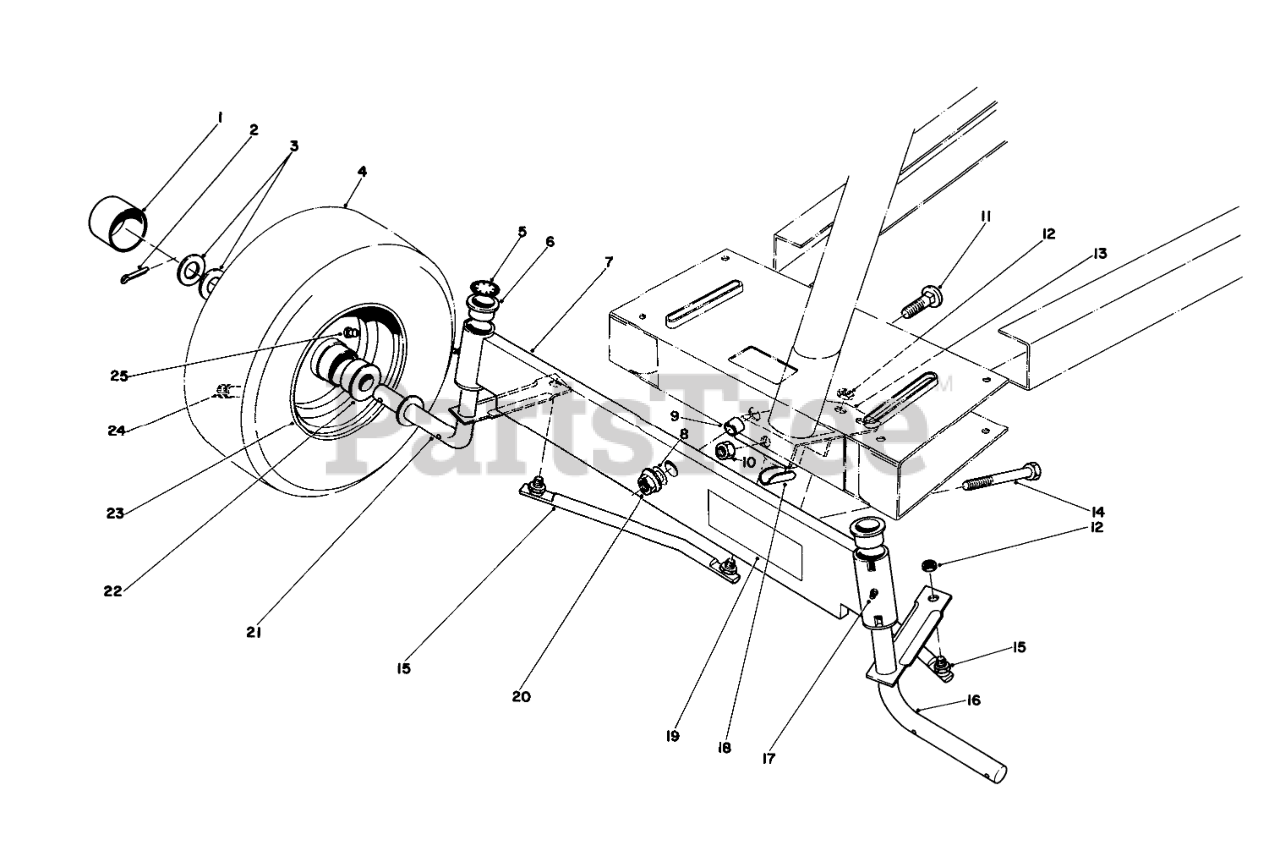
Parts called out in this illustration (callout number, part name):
1	Hub Cap
2	PIN-COTTER
3	WASHER-FLAT
4	Tire
5	RING-RETAINING
6	BUSHING
7	Front Axle
8	WASHER-THRUST
9	FRONT AXLE SPACER
10	NUT-LOCK, CONE
11	SCREW-CARR
12	NUT-LOCK, NI
13	Lever Steering
14	SCREW-HH
15	TIE ROD ASM
16	Spindle L.H.
17	GREASE FITTING
18	Spacer-Steering Tube
19	Decal-Warning
20	NUT-HF
21	SPINDLE WA RH
22	BUSHING
24	STEM-VALVE
25	FITTING-GREASE
